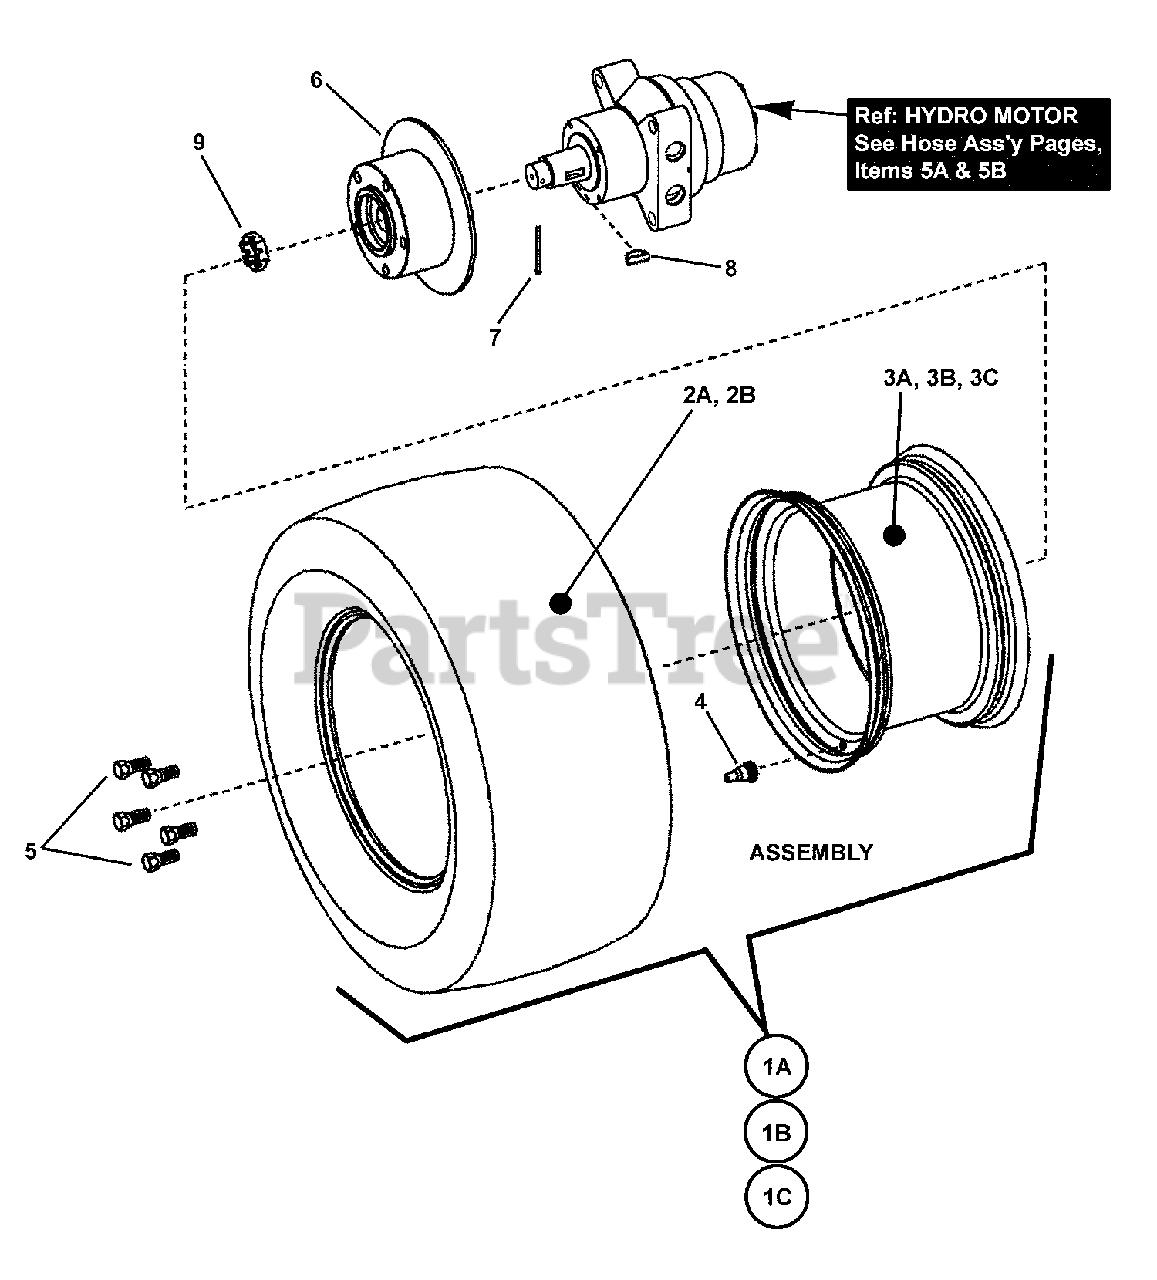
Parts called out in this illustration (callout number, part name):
1A	ASSEMBLY, Rear Tire & Rim (Incl. Items 2A, 3A & 4)
1B	ASSEMBLY, 23" Rear Tire & Rim (Incl. Items 2B, 3B & 4)
1C	ASSEMBLY, 24" Rear Tire & Rim (Incl. Items 2B, 3C & 4)
2A	TIRE, 23 x 10.5 - 12 NHS 4PR Kenda "Super Turf" 4 Ply
2B	TIRE, 23 x 10.5 - 12 NHS 4PR TMSTR TL (Carlisle)
3A	RIM, 12" Diameter x 7.00"
3B	RIM, 12" Diameter x 7.00"
3C	RIM, 12" Diameter x 8.50"
4	VALVE, Air
5	NUT, 1/2-20NF Lug
6	DRUM, Brake (Hayes)
6	DRUM, Brake (Ausco)
7	PIN, 9/64 x 1-1/2" Cotter
8	KEY, #11 Woodruff
9	NUT, 3/4-20 Slotted Hex
